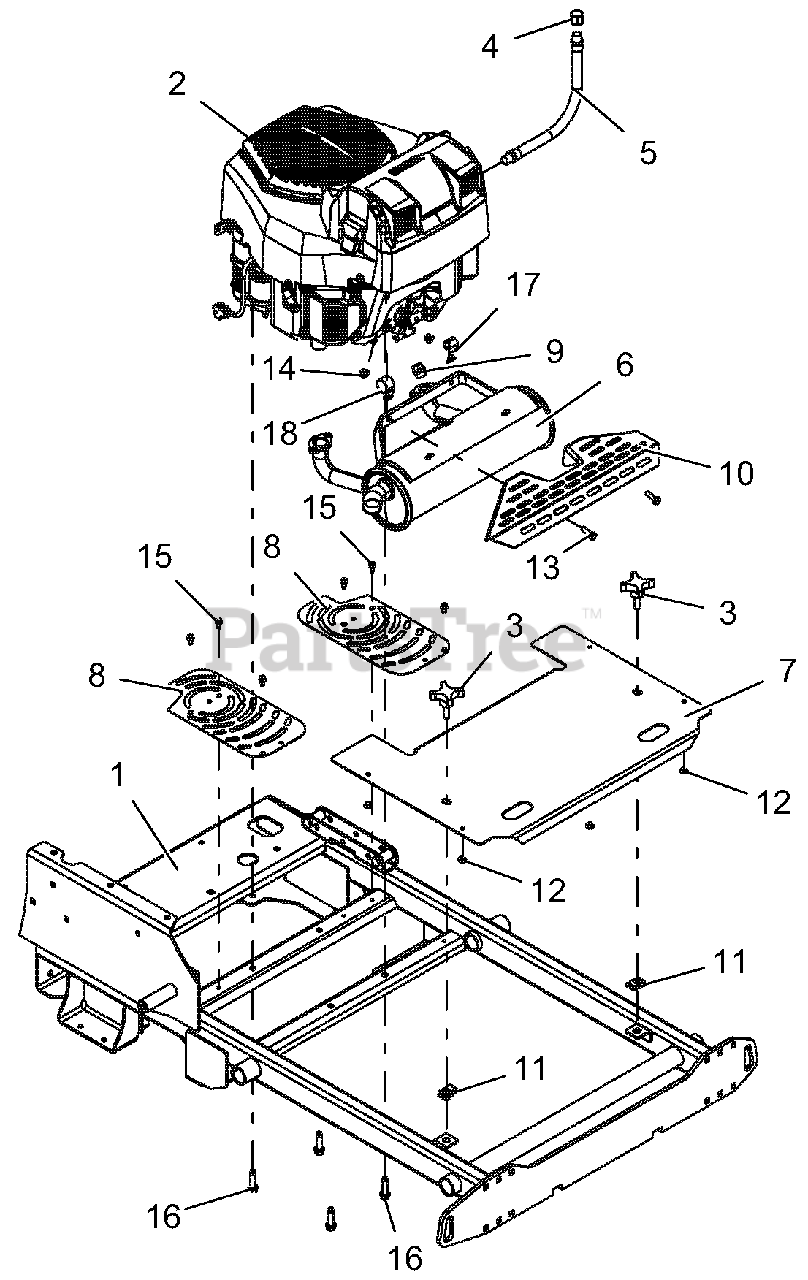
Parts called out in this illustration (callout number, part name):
1	WLDMT, FRAME PROSTANCE
2	ENGINE, KOHLER ZT730
3	KNOB, 3/8 X 1.25 - 4 PRONG
4	PIPE, CAP 3/8 NPT FEMALE
5	HOSE, HYD .38-11-OK M6N0-M6N0
6	MFLR, KOHLER
7	SHIELD, FRONT PRO-STANCE-RED
8	GUARD, FAN
9	PLUG, EXHAUST
10	GUARD, HEAT SHIELD (BLACK)
11	NUT, RTNR .375-16X.37
12	BUMPER GROMMET .125 X .25 REV
13	BLT-HEX .31-18X1.00 GR5 YWZC
14	NUT-LK-NYL-FLG .31-18 YWZC
15	SCR-TAP .25-20X.50 HWH TR YWZ
16	SCR-TAP .38-16X1.50 HWH TR YZ
18	CLAMP, CUSHIONED STEEL REV
